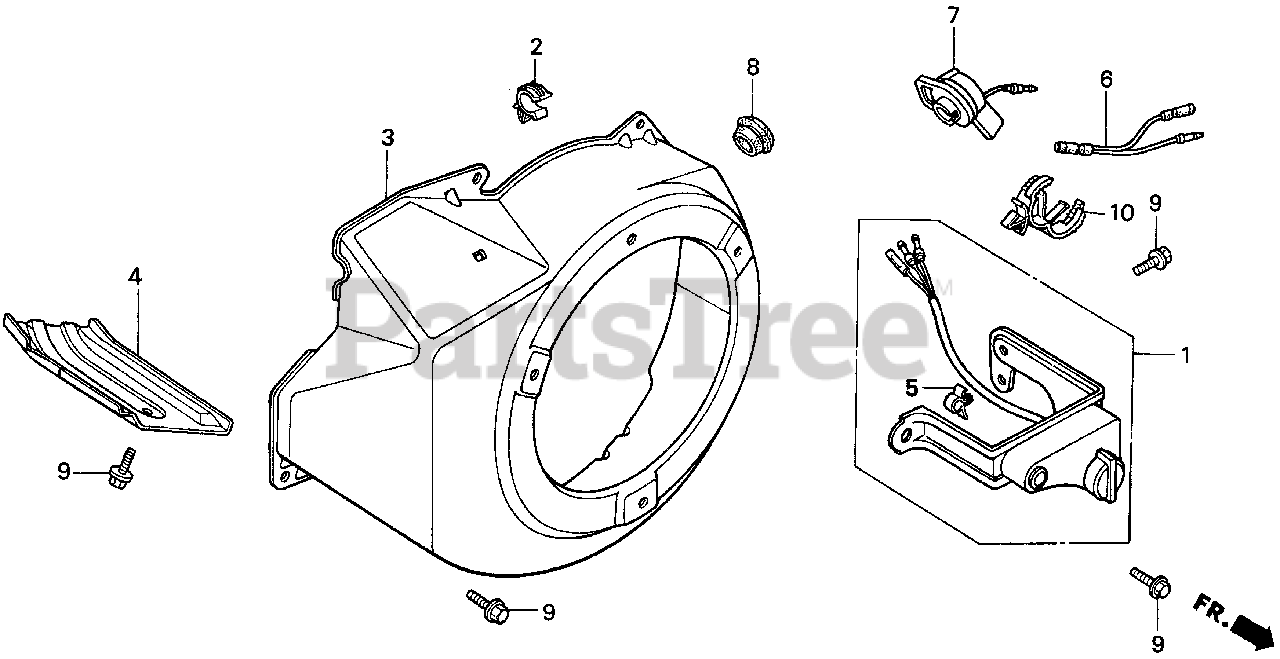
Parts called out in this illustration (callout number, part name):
1	ALERT UNIT, OIL
2	CLIP, TUBE
3	COVER, FAN *R8* (BRIGHT RED)
4	SHROUD
5	CLIP, IGNITION WIRE (8MM)
6	SUB-HARNESS
7	SWITCH ASSY., ENGINE STOP
8	GROMMET, DRAIN HOLE
9	BOLT, FLANGE (6X12) (CT200)
10	CLIP, WIRE HARNESS
